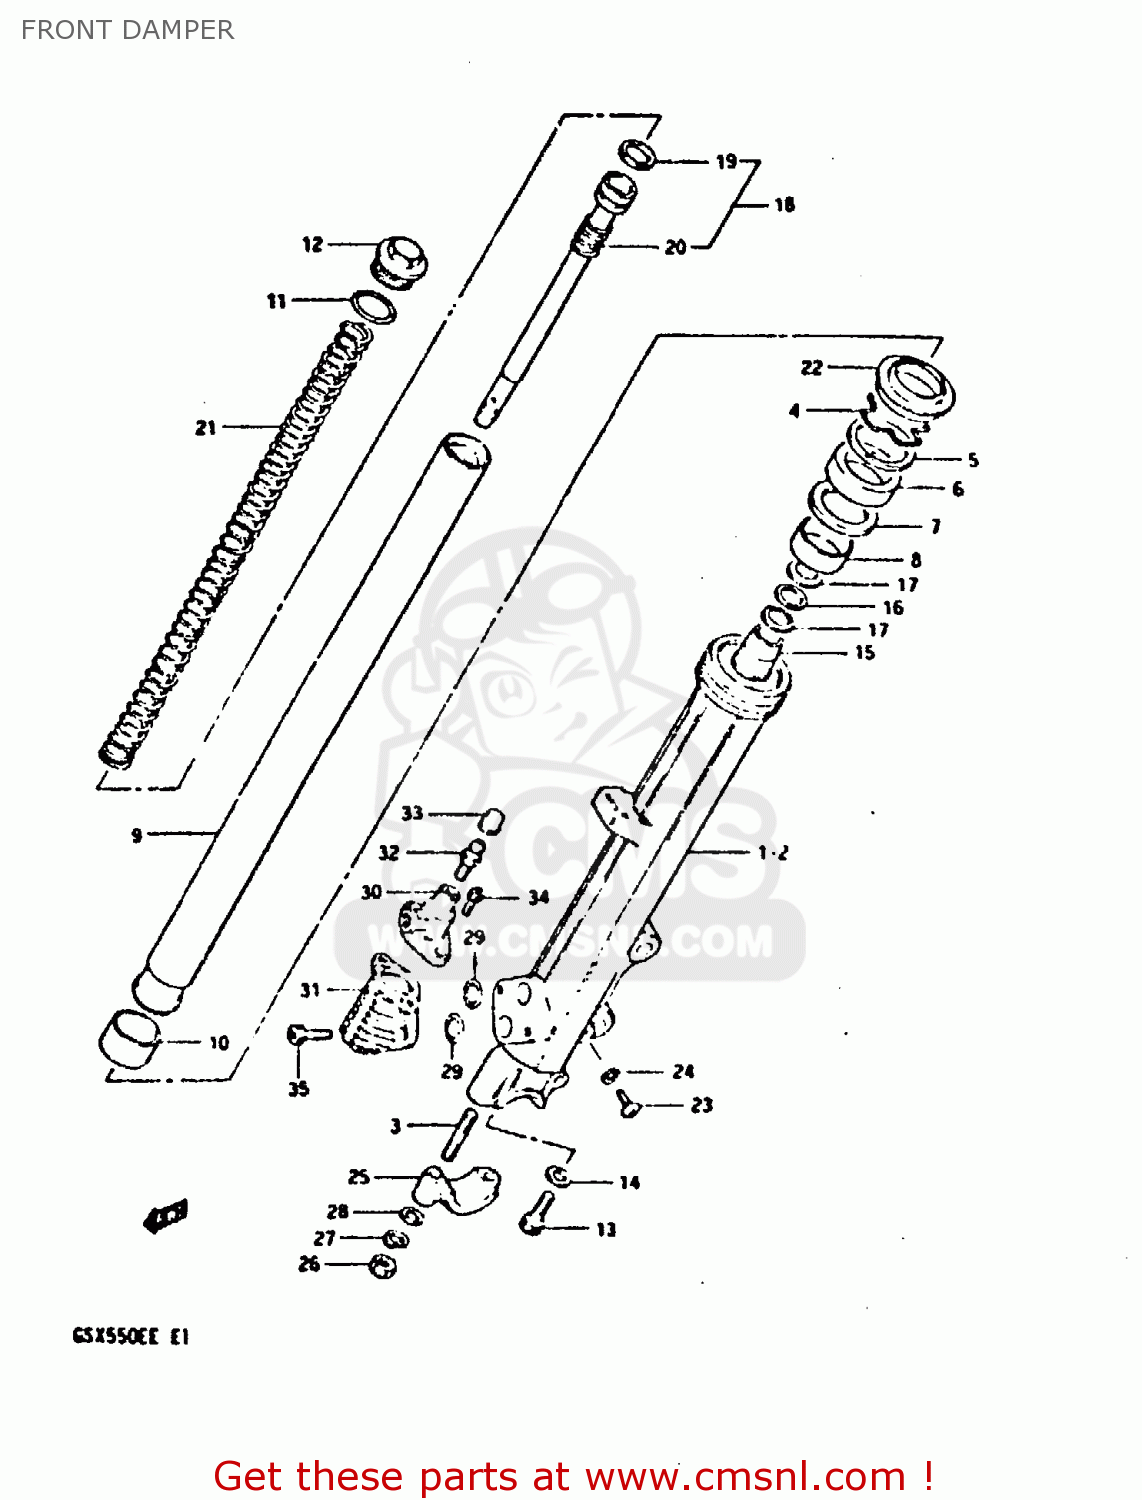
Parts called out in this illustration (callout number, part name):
1	TUBE,OUTER,RIGHT
2	TUBE,OUTER,LEFT
3	STUD 8X30
4	RING,STOPPER
5	WASHER. FRONT FORK
6	OIL SEAL,FRONT FORK
7	WASHER
8	METAL,SLIDE
9	INNER TUBE
10	METAL,FR FORK PISTON
11	O RING
12	CAP
13	BOLT,FORK CYLINDER(10X25)
14	GASKET (NAS)
15	PIECE,OIL LOCK
16	WASHER
17	SPRING,LEAF
18	CYLINDER,FRONT FORK
19	RING,PISTON
20	SPRING,REBOUND
21	SPRING
22	SEAL,DUST
23	SCREW
24	GASKET,DRAIN,PLUG (NAS)
25	HOLDER,AXLE
26	NUT
27	WASHER,LOCK,8.
28	WASHER
29	O RING
30	PLUNGER SET
31	PDF ASSEMBLY
32	BREATHER,AIR
33	CAP,BREADER
34	BOLT
35	BOLT
